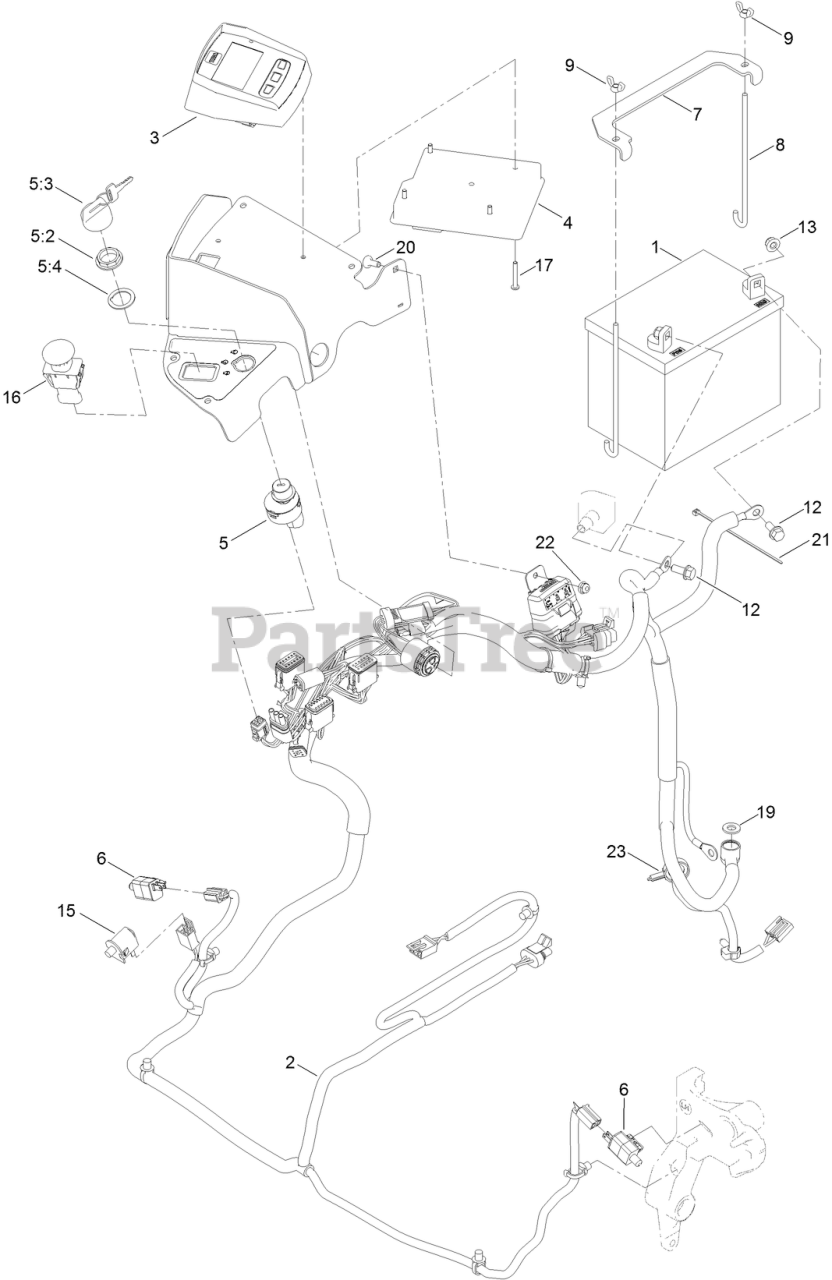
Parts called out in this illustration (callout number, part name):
1	BATTERY (340 CCA, WET)
2	HARNESS-WIRE
3	MODULE-HORIZON
4	MODULE-MCU
5	IGNITION SWITCH ASM
5:2	NUT-MOUNTING
5:3	IGNITION KEY SET
5:4	WASHER-BACKUP
6	SWITCH
7	STRAP-TIE DOWN, BATTERY
8	BOLT-HOLDDOWN
9	WINGNUT
12	SCREW-HHF
13	NUT-HF, NI
15	SWITCH-BAIL
16	SWITCH-PTO, SEALED
17	SCREW-PPH
19	WASHER-FLAT
20	BOLT-CARR
21	TIE-CABLE
22	NUT-HF
23	CLAMP-HOSE
